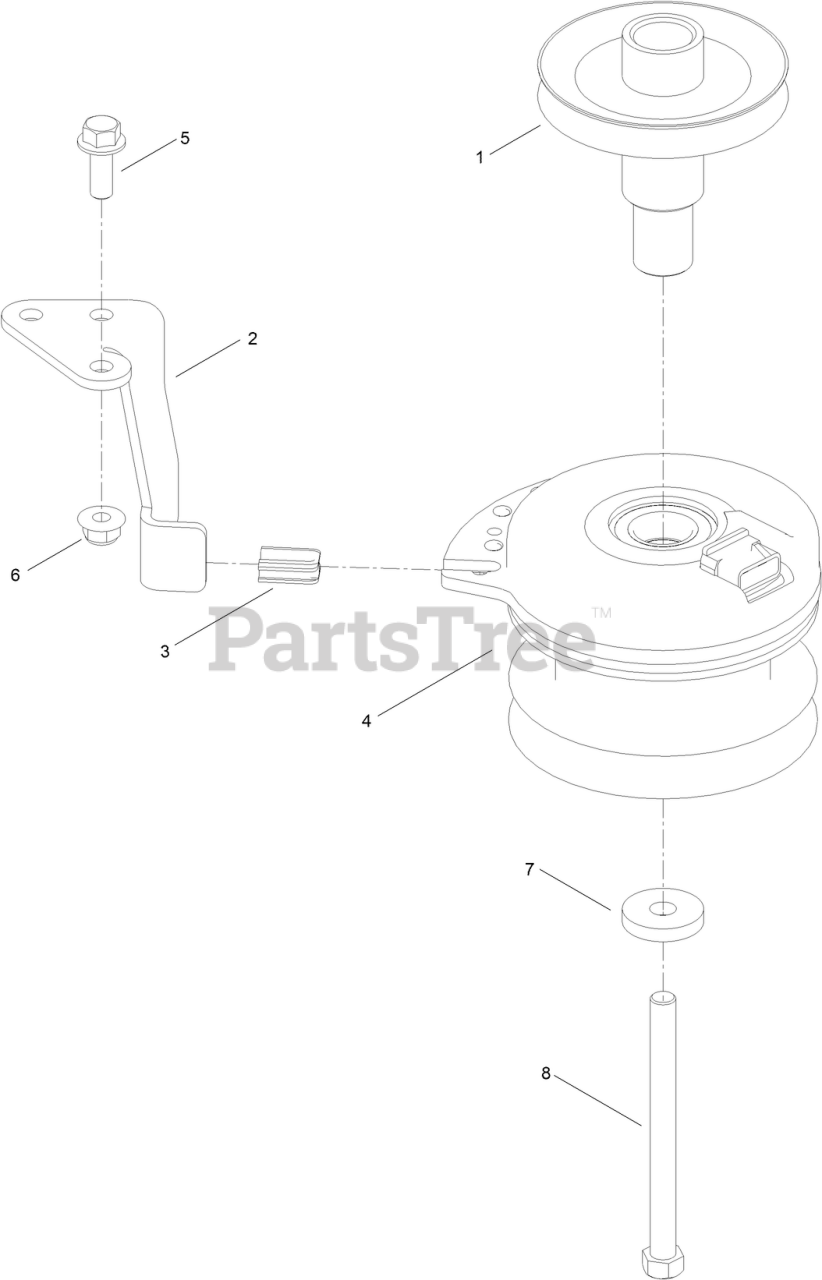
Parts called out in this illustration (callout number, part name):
1	PULLEY-ENGINE
2	STOP - CLUTCH (NARROW)
3	ISOLATOR-CLUTCH
4	CLUTCH-PTO
5	SCREW-HHF
6	NUT-HF, NI
7	WASHER
8	SCREW-HH
